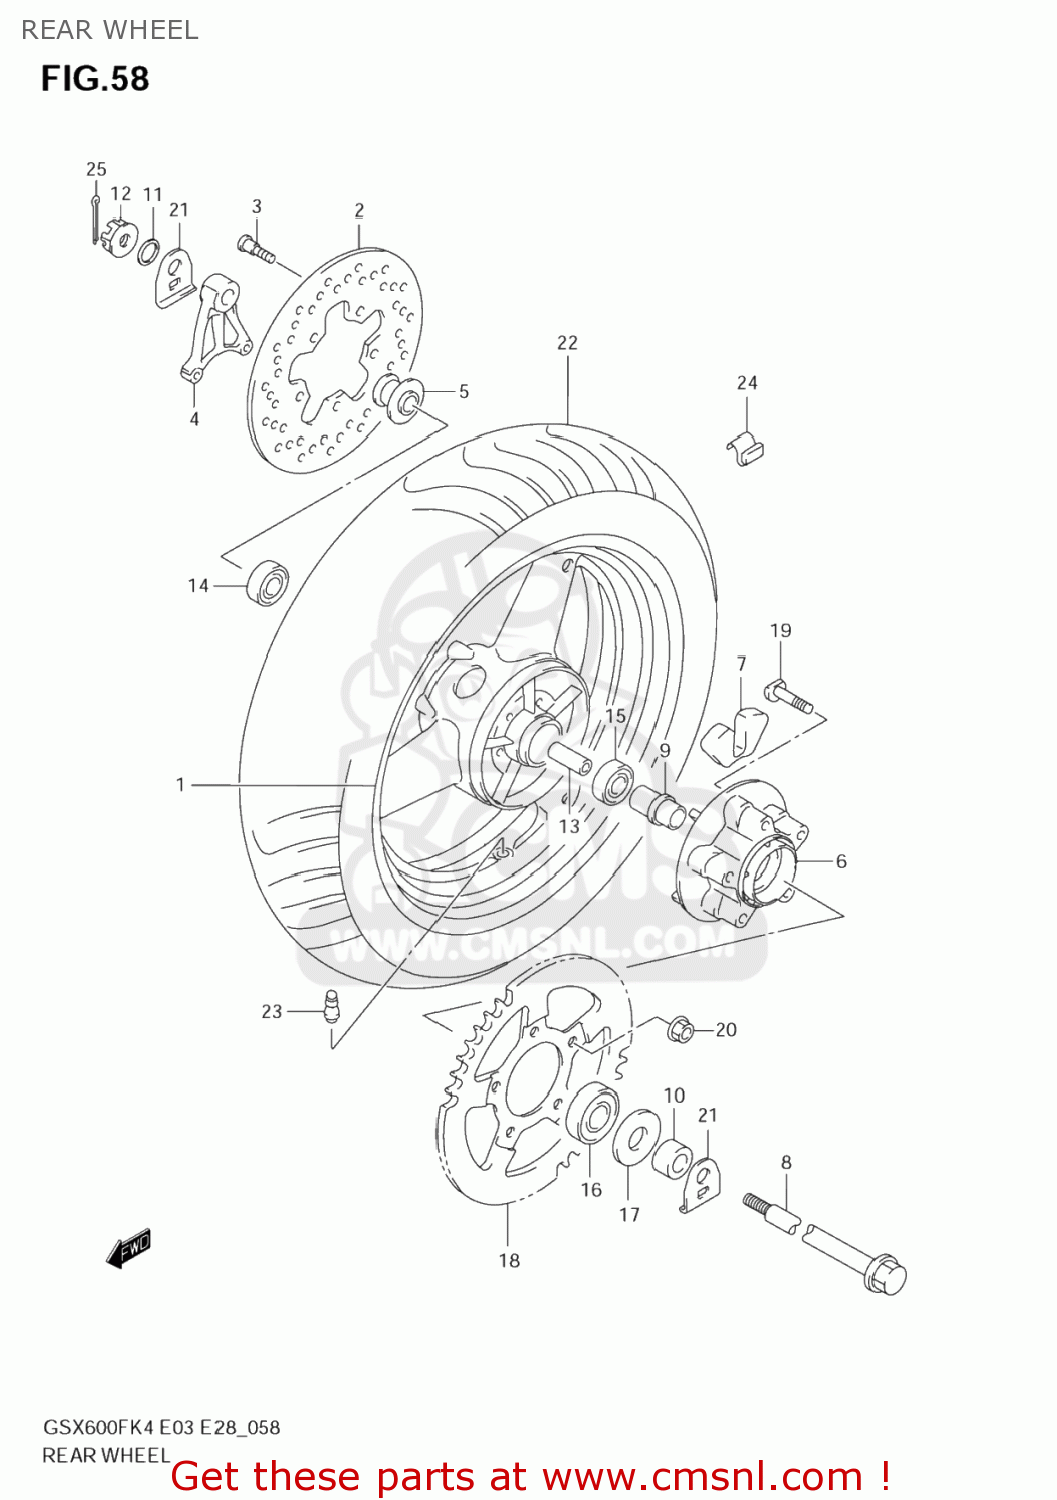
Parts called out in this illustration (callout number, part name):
1	WHEEL,RR(17M/CXMT4.50)
2	DISC,RR BRAKE
3	BOLT 8X33
4	BRACKET,RR CALIPER
5	SPACER,RR AXLE,R
6	DRUM,RR SPROCKET
7	ABSORBER,RR HUB SHOCK
8	AXLE,RR
9	RETAINER,RR SPROCKET DRUM
10	SPACER,RR AXLE,R
11	WASHER(17X30X3.2)
12	NUT
13	SPACER(17.5X25X88)
14	BEARING
15	BEARING
16	BEARING(25X62X17)
17	SEAL,OIL(35X62X8)
18	SPROCKET,RR(NT:47-530)
19	BOLT(10X47)
20	NUT
21	WASHER,CHAIN ADJUSTER
22	TIRE,RR(150/70 ZR17 69W)
23	VALVE ASSY,WHEEL RIM(TR412)
24	BALANCER,WHEEL(10G)
25	PIN,COTTER
